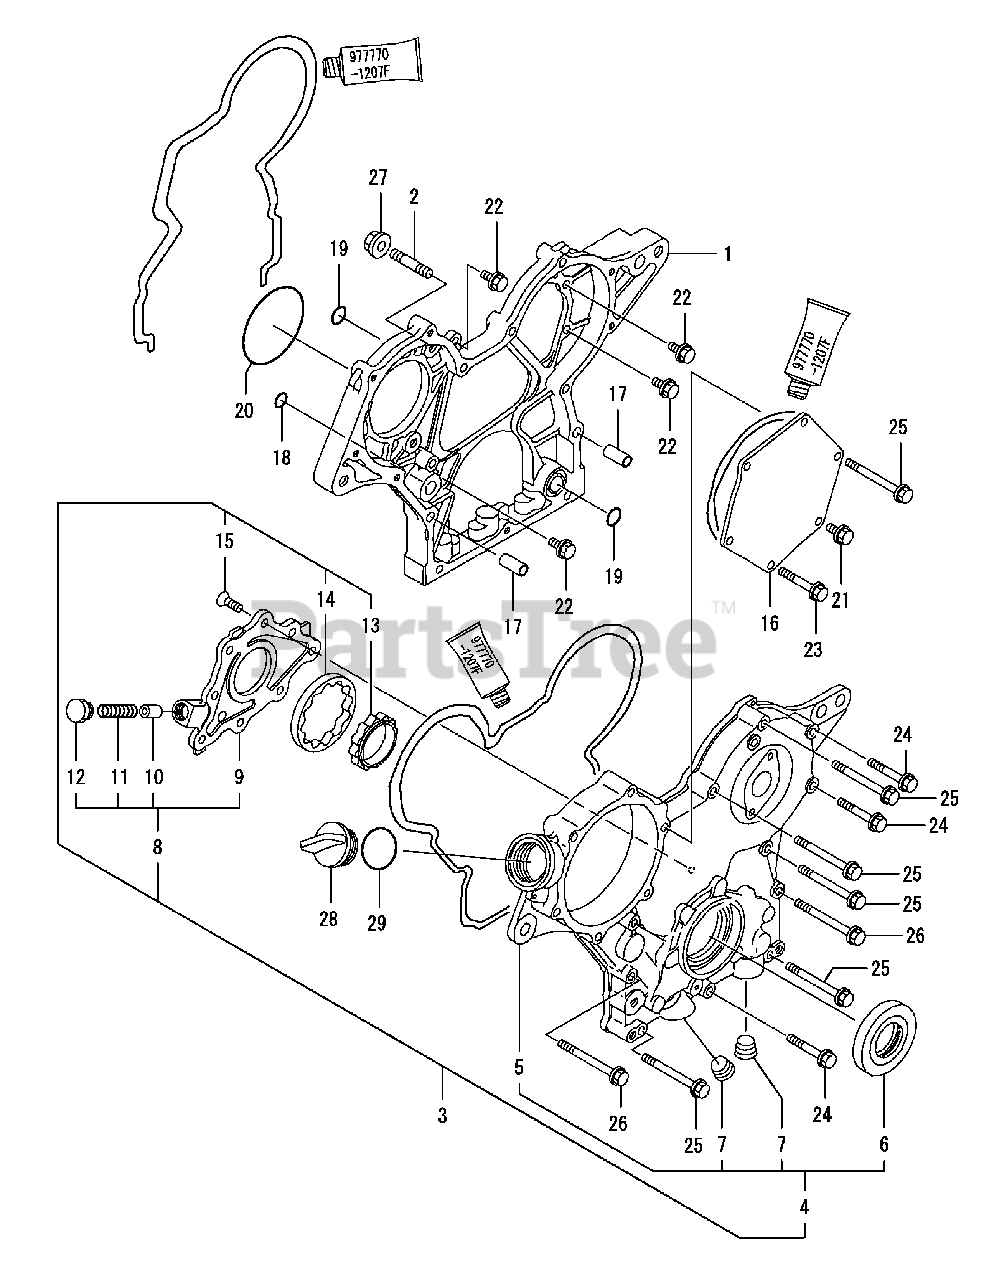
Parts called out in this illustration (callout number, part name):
3	Cover Assembly, Gear Case
4	Cover Assembly, Gear Case
5	Cover, Gear Case
7	Plug Pt, 3/8, Screw
8	Cover Assembly, Pump
9	Cover, Lub. Oil Pump
15	Screw, M6 x 16
16	Cover, Pump Timing
20	O-Ring, F.I. Pump
21	Bolt M 6 x 12 Plated
22	Bolt M 6 x 16 Plated
23	Bolt M 6 x 40 Plated
24	Bolt M 6 x 40 Plated
25	Bolt M 6 x 60 Plated
26	Bolt M 6 x 65 Plated
29	O-Ring 1A P-32.0
